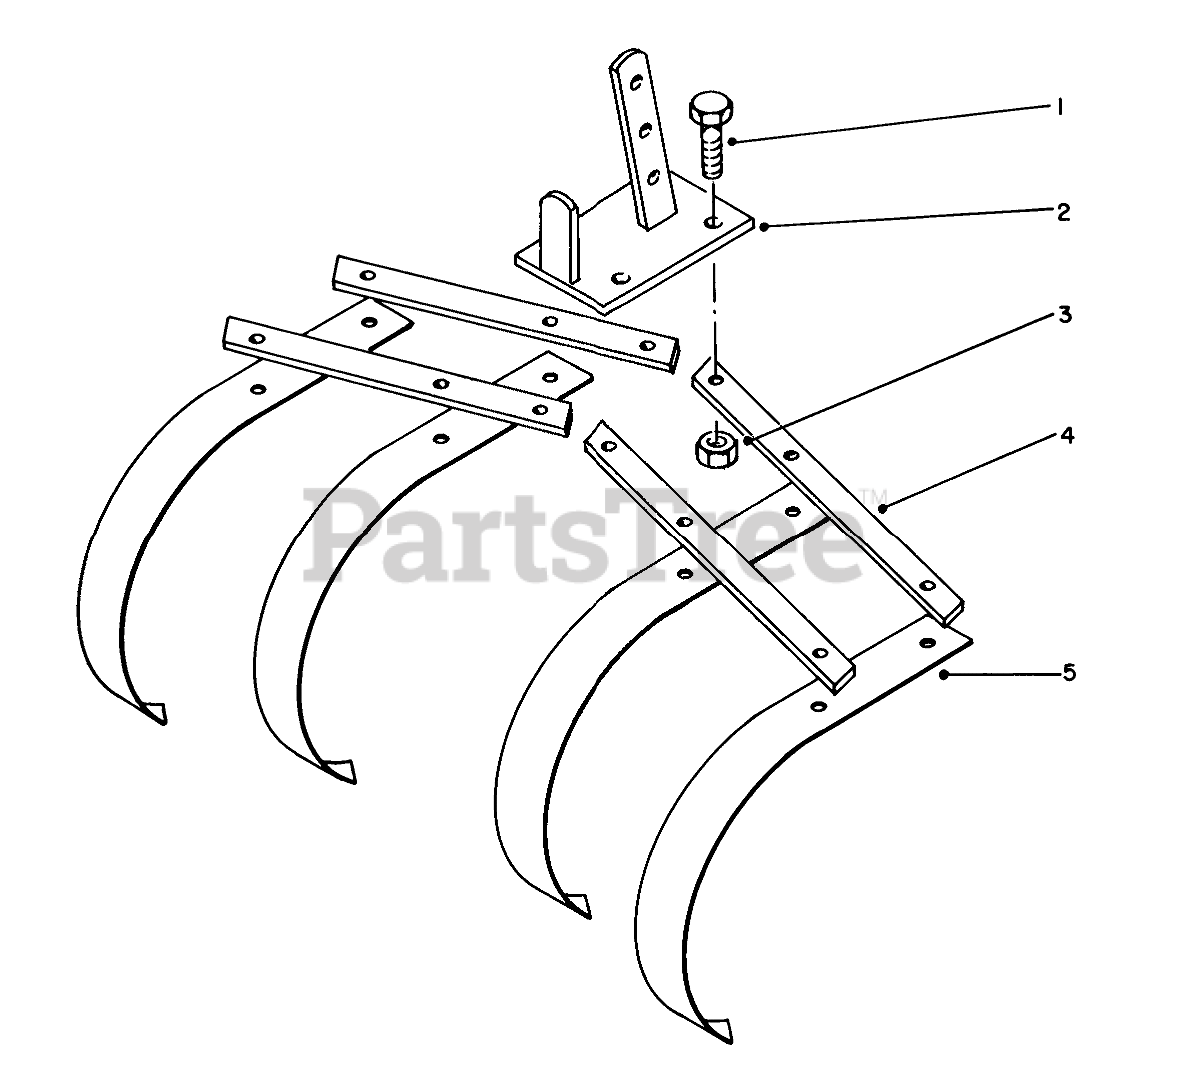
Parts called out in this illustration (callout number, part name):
1	SCREW-HH
2	Hitch
3	NUT-LOCK, CONE
4	Attachment Bar
5	Spring Tooth
